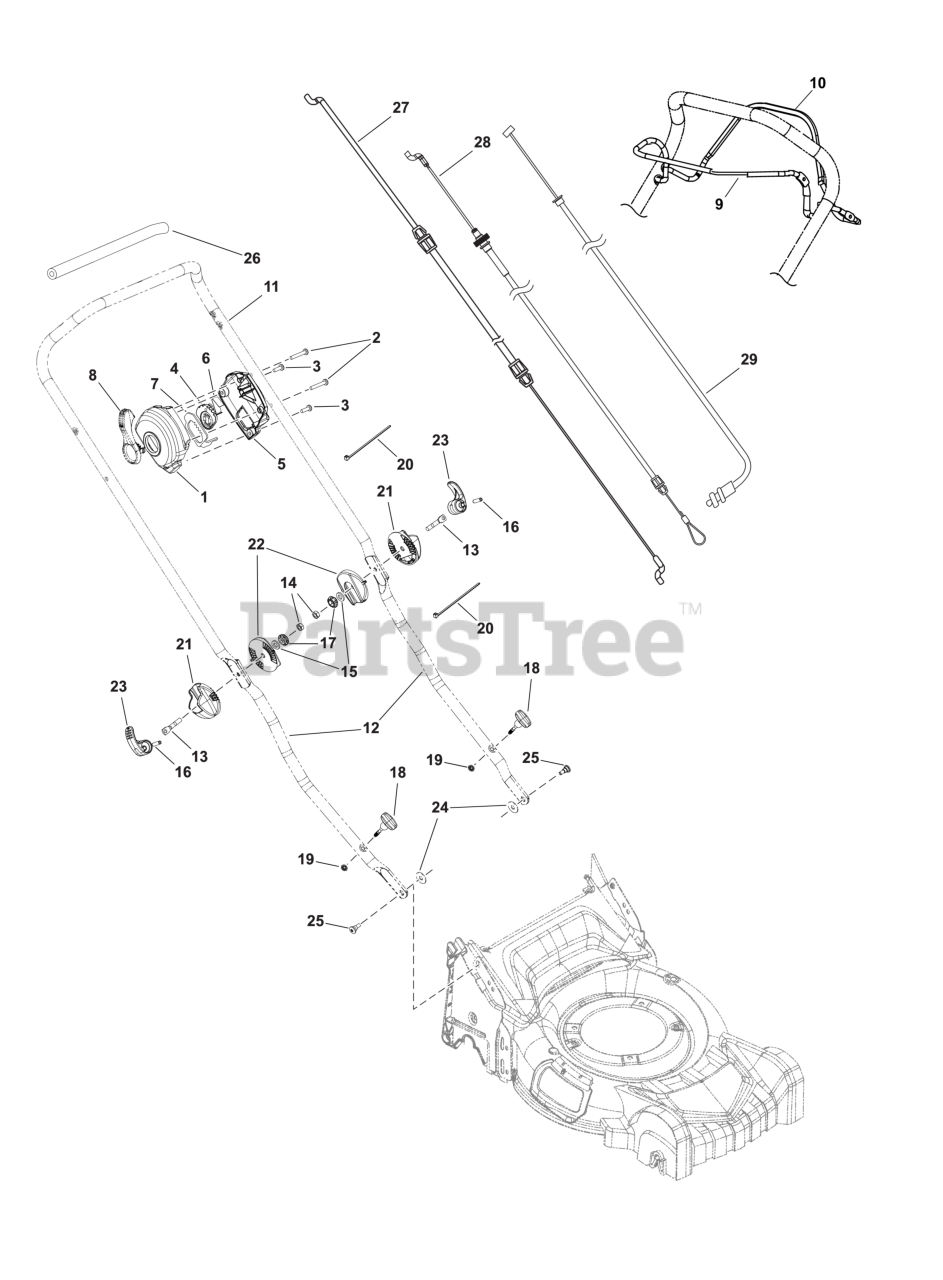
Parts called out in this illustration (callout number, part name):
1	CONTROL HOUSING, Upper
2	SCREW, 184-15 x 1-1/2
3	SCREW, 184-15 x 3/4
4	SPEED ACTUATOR
5	CONTROL HOUSING, Lower
6	SPRING, Shift
7	RACK PLATE
8	LEVER, Speed Select
9	BAIL, Control, Red
10	BAIL, Drive
11	HANDLE, Upper
12	HANDLE, Lower
13	BOLT, Eye
16	PIN, Spring
18	BOLT, Wing
19	CLAMP RING
20	CABLE CLIP
21	SUPPORT, Handle, Outer
22	SUPPORT, Handle, Inner
25	BOLT, Shoulder
26	SOFT GRIP
27	CABLE, Control
28	CABLE, Drive
29	CABLE, Speed Select
